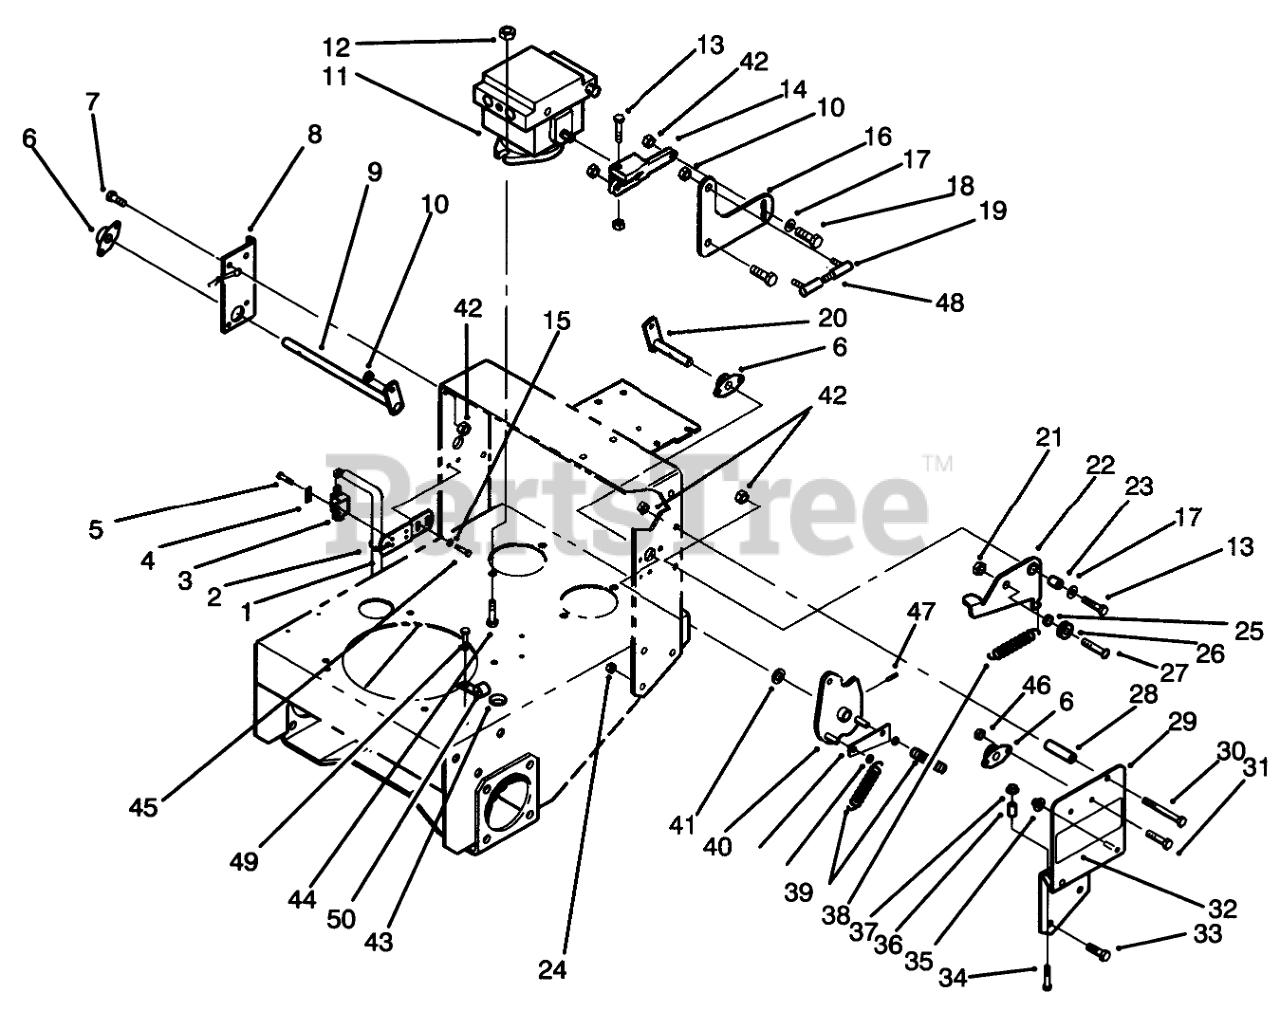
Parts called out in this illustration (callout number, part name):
1	NEUTRAL BRACKET B
2	TIE-CABLE
3	SWITCH-POLE, SINGLE
4	PLATE-SWITCH
5	SCREW-TAPTITE
6	SIDE FLANGE BEARING ASM
7	SCREW-HH
8	Bracket-Bushing
9	RH LEVER WA
10	NUT-LOCK, NI
11	HYDRAULIC PUMP
12	NUT-HF
13	SCREW-HH
14	ARM-PUMP
15	WASHER-FLAT
16	FOLLOWER ARM B
17	WASHER-PLAIN
18	SCREW-HH
19	JOINT-BALL
20	LH LEVER WA
21	NUT-LOCK, NI
22	Detent Arm Assembly L.H.
23	BUSHING-ARM, DETENT
24	NUT-LOCK, NI
25	SPACER-BEARING
26	BEARING-BALL
27	SCREW-HSBH
28	STOP-REVERSE
29	LEFT BRACKET WA R
30	SCREW-HH
31	SCREW-HH
32	DECAL-HYDRO
33	SCREW-HH
34	SCREW-HH
35	NUT-PUSH
36	SPACER-TUBULAR
37	NUT-LOCK, HHF
38	SPRING-DETENT
39	SPRING-EXTENSION
40	Pivot Assembly L.H.
41	WASHER-THRUST
42	NUT-LOCK, NI
43	GROMMET
44	SCREW-HH
45	Screw
46	NUT-LOCK, NI
47	PIN-ROLL, SLOTTED
48	BALL JOINT ROD
49	SCREW-HWH
50	CLAMP-R
51	NUT-PUSH IN
52	STOP BRACKET
